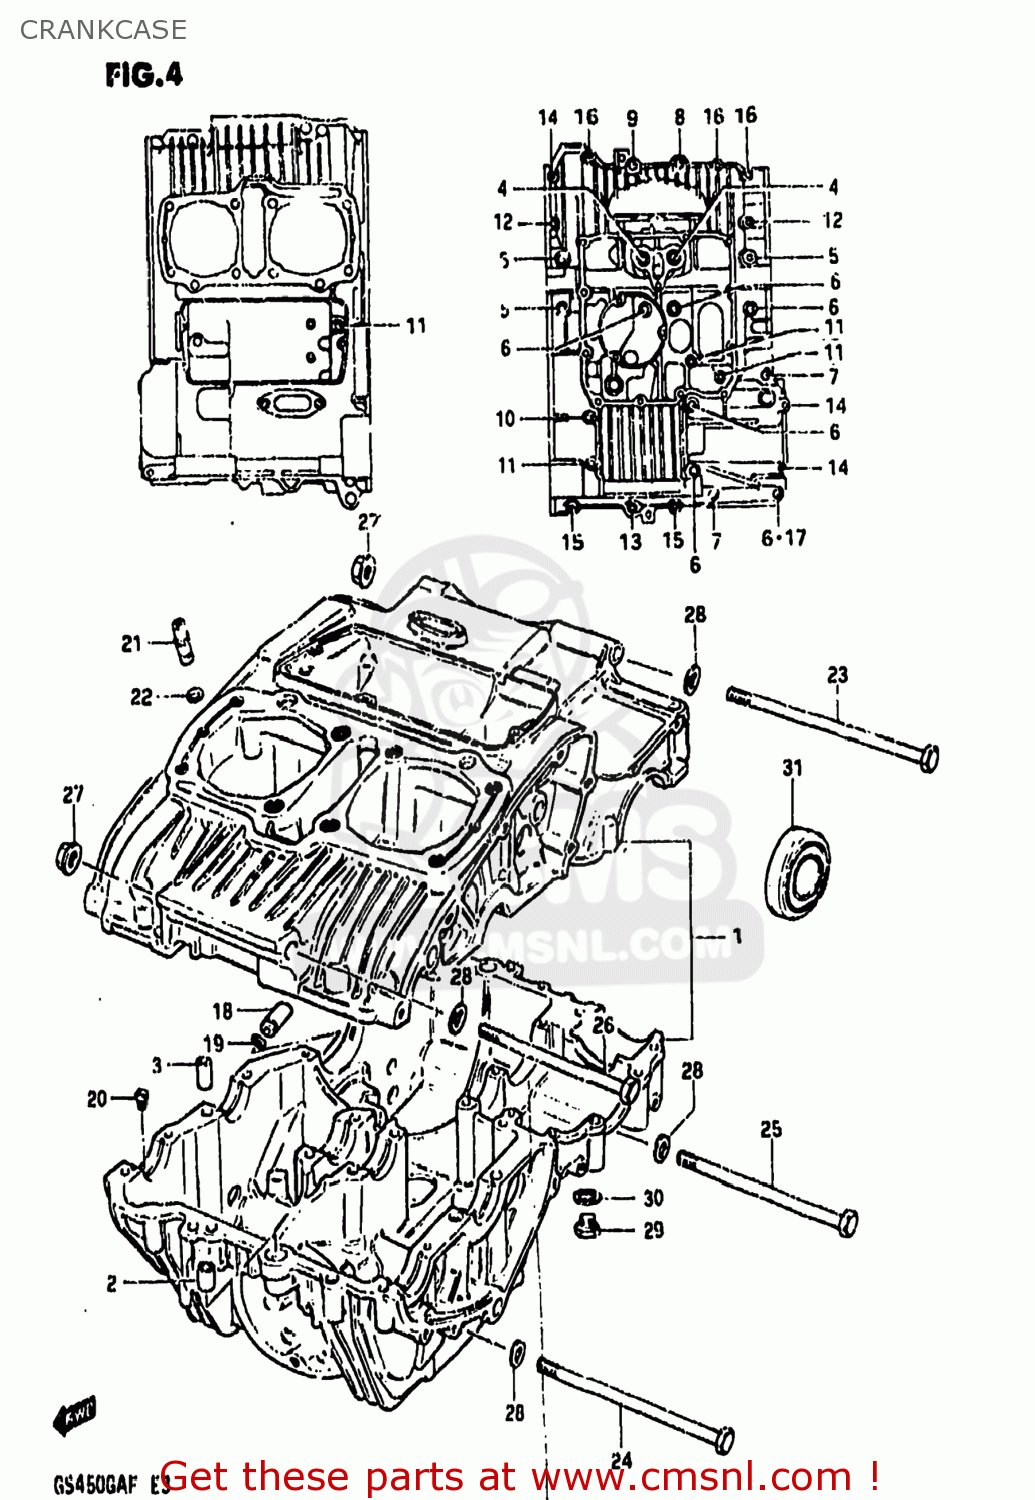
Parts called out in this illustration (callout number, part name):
1	CRANKCASE SET
2	PIN(10.4X13X22)
3	PIN (11X20)(SUS)
4	BOLT (8X70)
5	BOLT
6	BOLT
7	BOLT (8X70)
8	BOLT (8X65)
9	BOLT
10	BOLT
11	BOLT(6X105)
12	BOLT (6X90)
13	BOLT
14	BOLT
15	BOLT 6X50
16	BOLT (6X45)
17	NUT 8MM
18	VALVE ASSEMBLY,PISTON OIL
19	O-RING
20	JET,AIR
21	JET(12)
22	O RING(D:1.2,ID:4)
23	BOLT
24	BOLT
25	BOLT
26	BOLT
27	NUT 10MM
28	WASHER
29	PLUG
30	GASKET(14X19.2X2) (NAS)
31	PLUG
